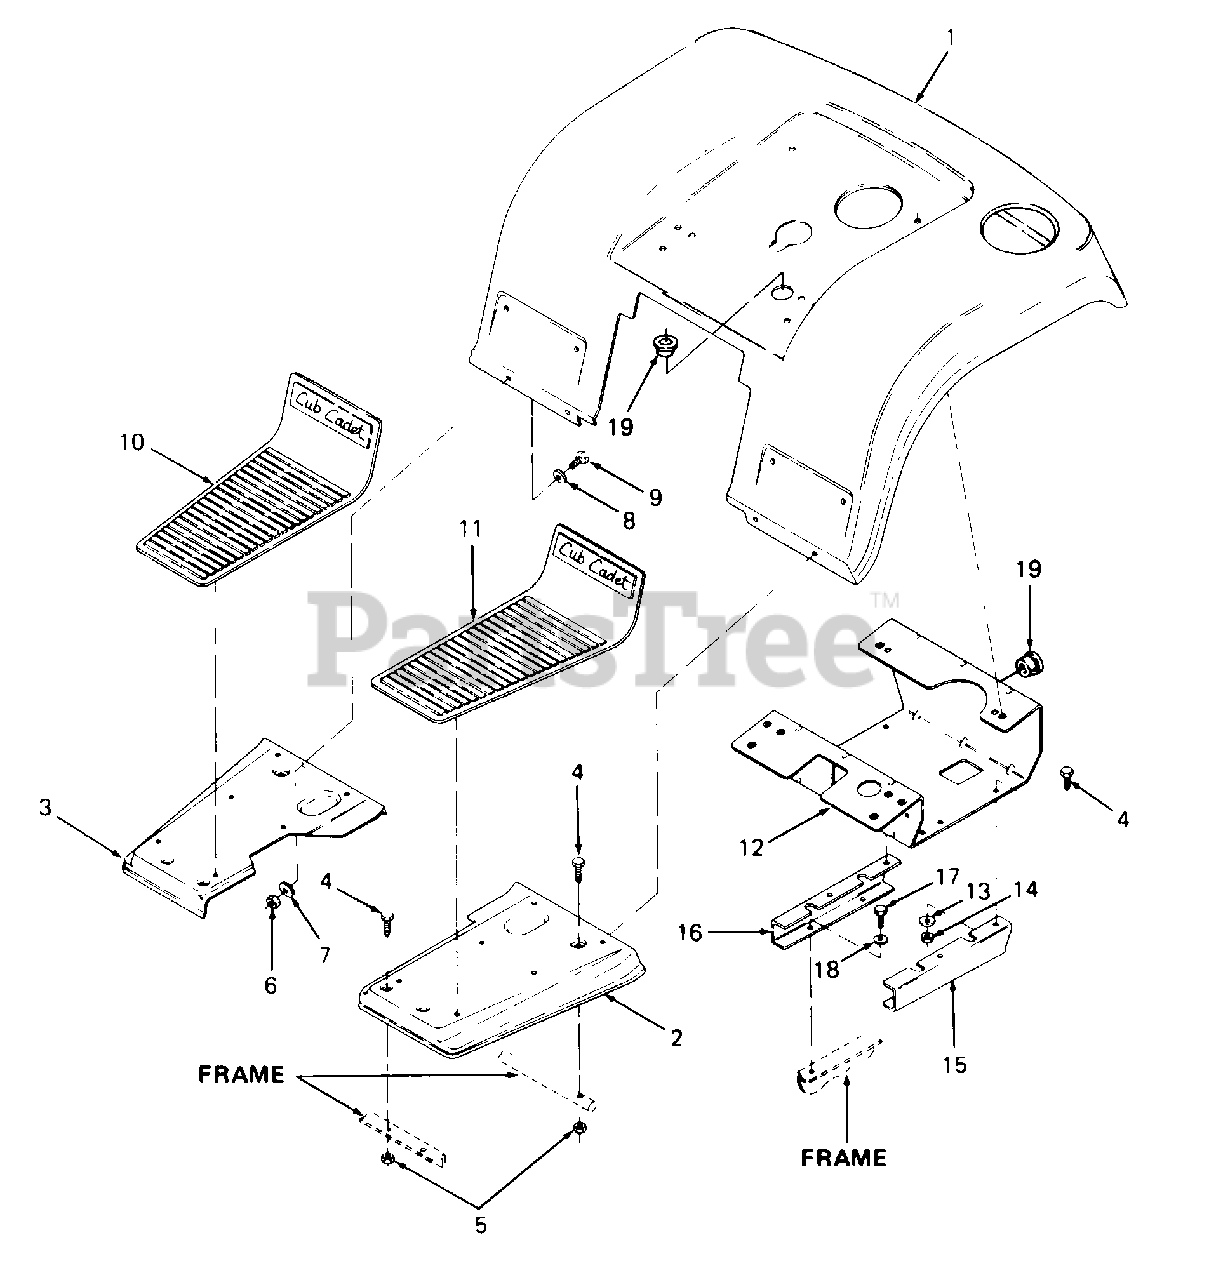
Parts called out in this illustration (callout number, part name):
5	Nut, Hex Center Lock, 5/16-18 GR5
6	Nut, Hex Patch Lock, 1/4-20
7	Washer, Bell, .265 X .75 X .062 Thk
8	Washer, Flat, .281 X .73 X .063 Thk
9	Screw, Hex, Cap, 1/4-20 X .50 Lg GR5
10	Foot Pad - RH
11	Foot Pad - LH
13	Washer, Bell, .345 X .88 X .060 Thk
14	Nut, Hex, 5/16-18 GR5.
15	Support Bracket, Fender - LH
16	Support Bracket, Fender - RH
17	Screw, Hex Cap, 5/16-18 X .62 Lg GR5
18	Washer, Flat, 34 X 68 X .062 Thk
19	Bushing, Snap
